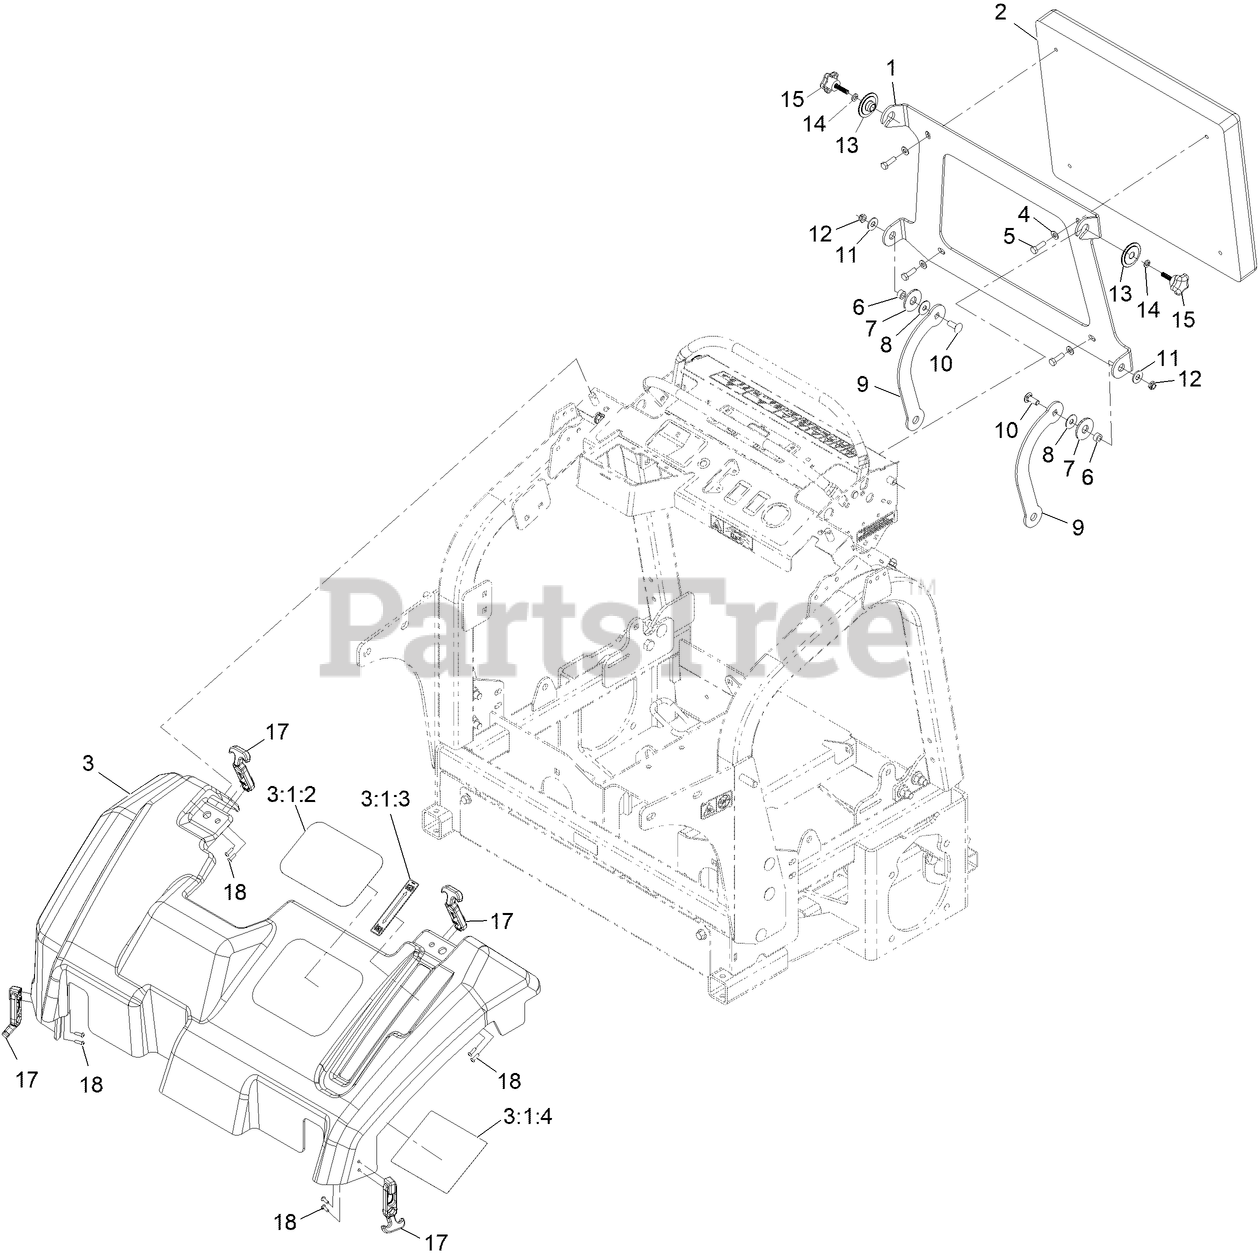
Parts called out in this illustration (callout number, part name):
1	HINGE-PAD
2	PAD-CUSHION
3	COVER TOP ASM W/DECALS
3:1:2	DECAL-Z TURF EQUIPMENT
3:1:3	DECAL-BRAKE, PARKING
3:1:4	DECAL-SERVICE AID
4	WASHER-PLAIN
5	SCREW-HH
6	SPACER
7	WASHER-FRICTION, COMPOSIT
8	Washer-Flat
9	LINK-PLATFORM
10	SCREW-CARR
11	WASHER-FLAT
13	SLIDE-BUSHING
14	WASHER-LOCK
17	LATCH-RUBBER
18	SCREW-HSBH
